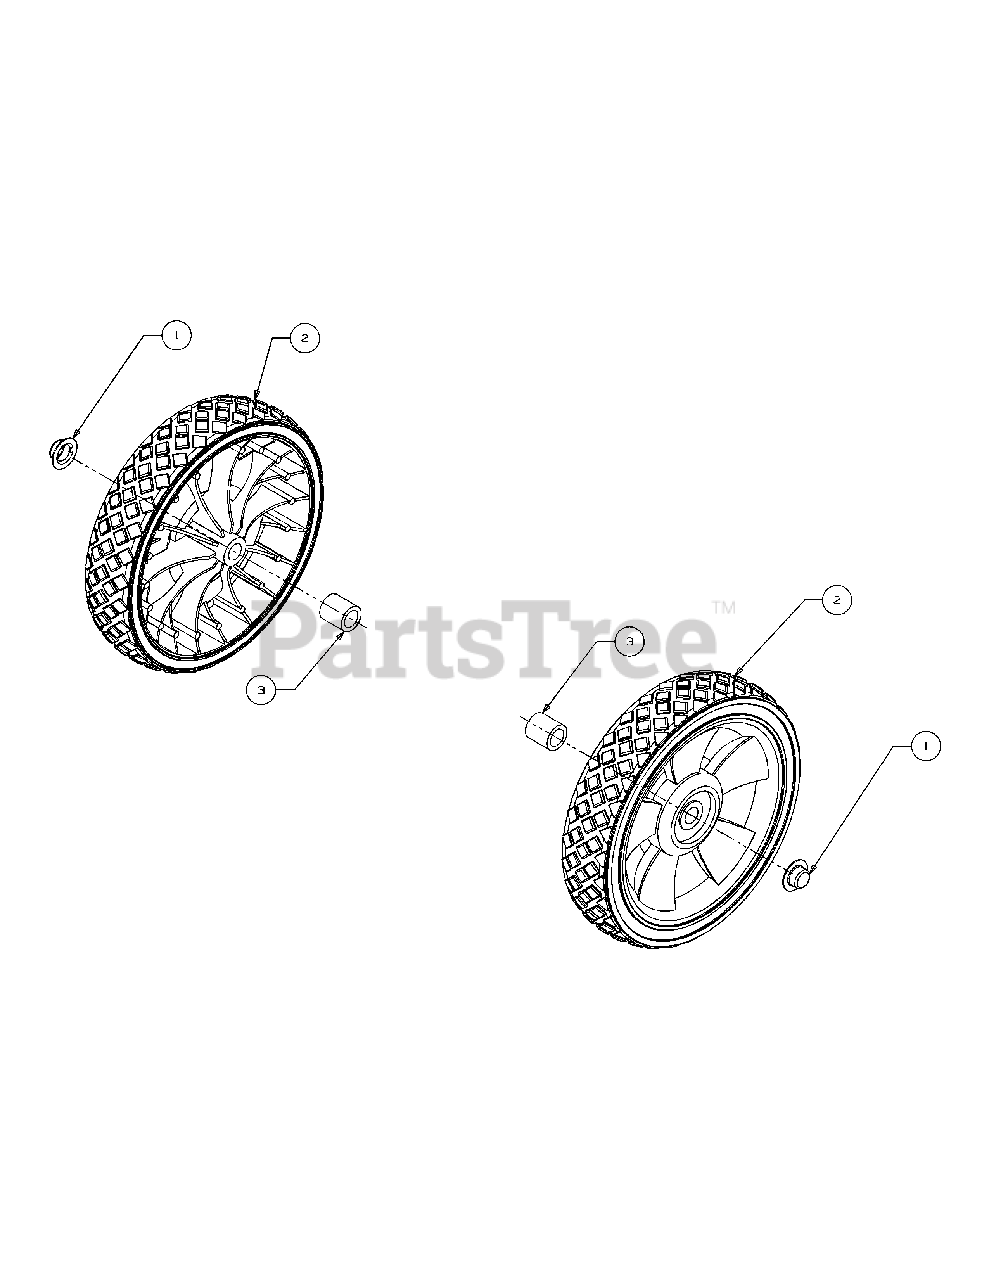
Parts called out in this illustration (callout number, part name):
1	Push Cap
2	Wheel-Complete 8"
3	Spacer .525 X .775
